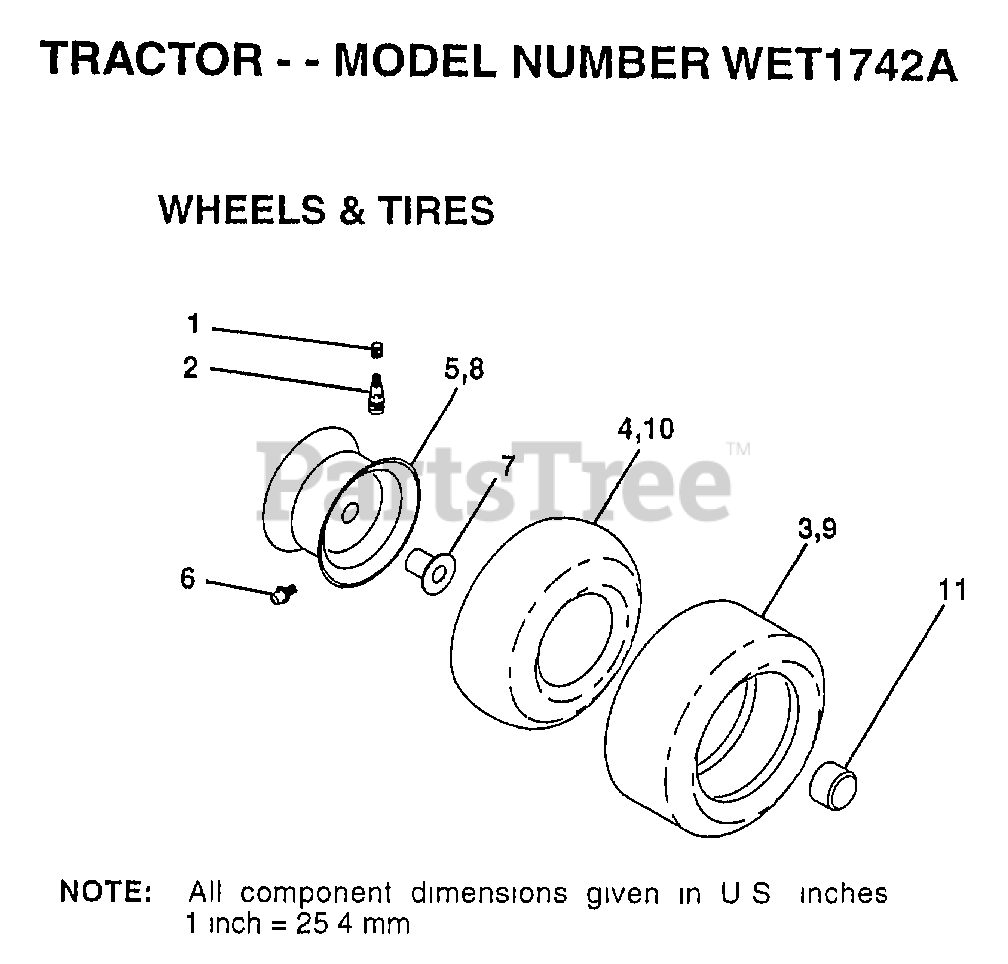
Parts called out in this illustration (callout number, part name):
1	VALVE CAP
2	VALVE STEM LT
4	TUBE.5.3/4.5/6
5	"RIM ASM 6"" FRT"
6	FITTING LT
7	"FLANGE, BEARING"
8	"RIM AS 8"" REAR"
9	TIRE.20X8-8
10	TUBE.18X9.5-8
11	HUB CAP
